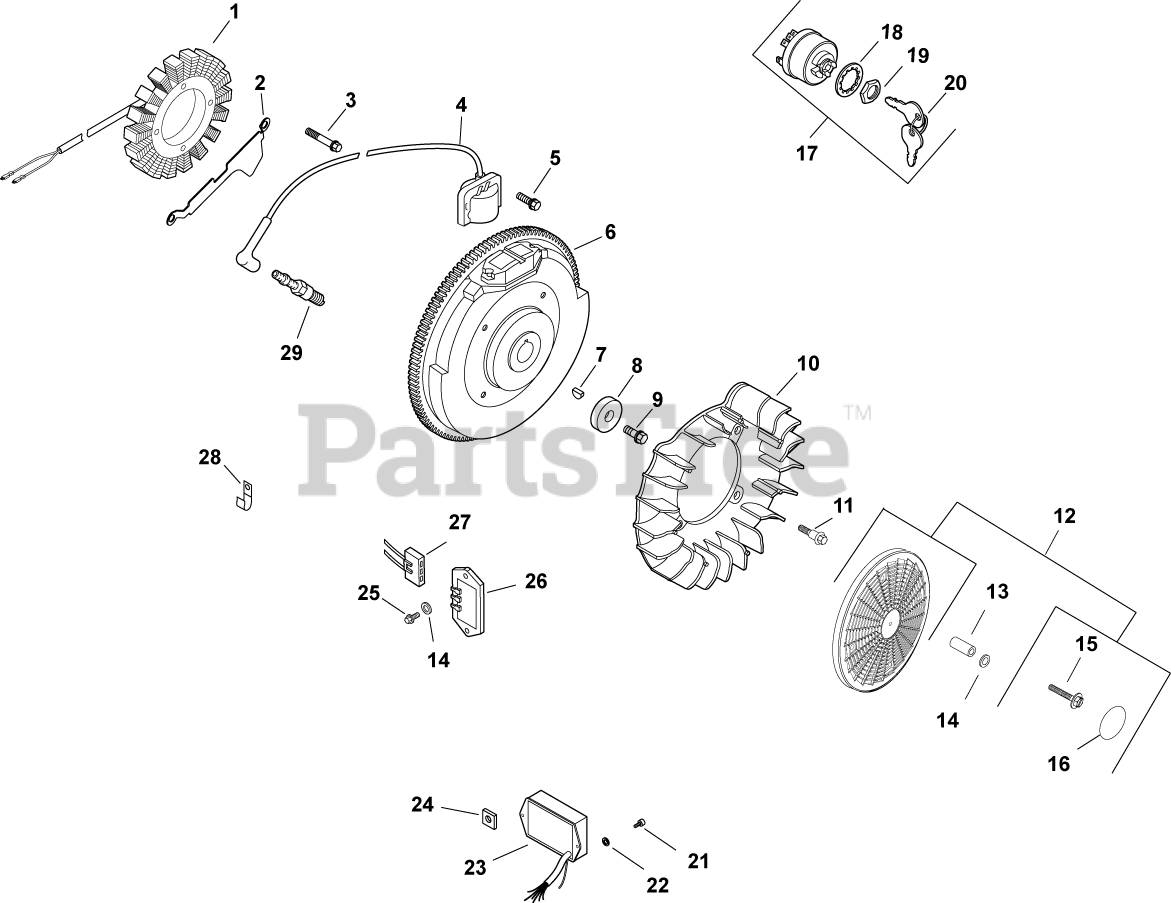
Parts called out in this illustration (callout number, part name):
1	KIT, 15 / 20 AMP STATOR
2	BRACKET, STATOR WIRE
3	SCREW, M5X0.8X25 - (#25086402S)
4	MODULE, IGNITION
5	SCREW, SKT THD FRM M5X0.8X25
6	FLYWHEEL, PAINTED-USE 24 025 57-S
7	KEY, 3/16" X 5/8"
8	WASHER, FLAT 13/32"
9	SCREW, FLG M10X1.5X45 - (#25086361S)
10	FAN USE 24 157 11-S
11	BOLT, SHOULDER
12	KIT, GRASS SCREEN
13	SPACER - DISCONTINUED
14	WASHER, FLAT 3/16"
15	SCREW, SLT HD CAP M4X0.7X25
16	DECAL, GRASS SCREEN USE 24 113 499-S
17	SWITCH ASSY, KEY (KM)-USE 25 099 32-S
18	WASHER, INTERNAL TOOTH
19	NUT, KEY SWITCH
20	KEY, SET -USE 48 340 01-S
21	SCREW, PHL HD #11-16X1/2"
22	WASHER, FLAT 1/4" (O.D. 1/2")
23	MODULE, SPEED ADVANCE-DISCONTINUED SEE PB265
24	NUT, PLASTIC
25	SCREW, PHL HD #11-16X7/8"
26	REG/RECT-15 AMP (KM)-USE 41 403 10-S
27	CONNECTOR, BODY (KM)-USE 25 155 41-S
28	CLIP, CABLE
29	PLUG, SPARK (STD)
2545403-S	TIE, WIRE
X-22-11-S	WASHER, INT TOOTH LOCK 1/4"
